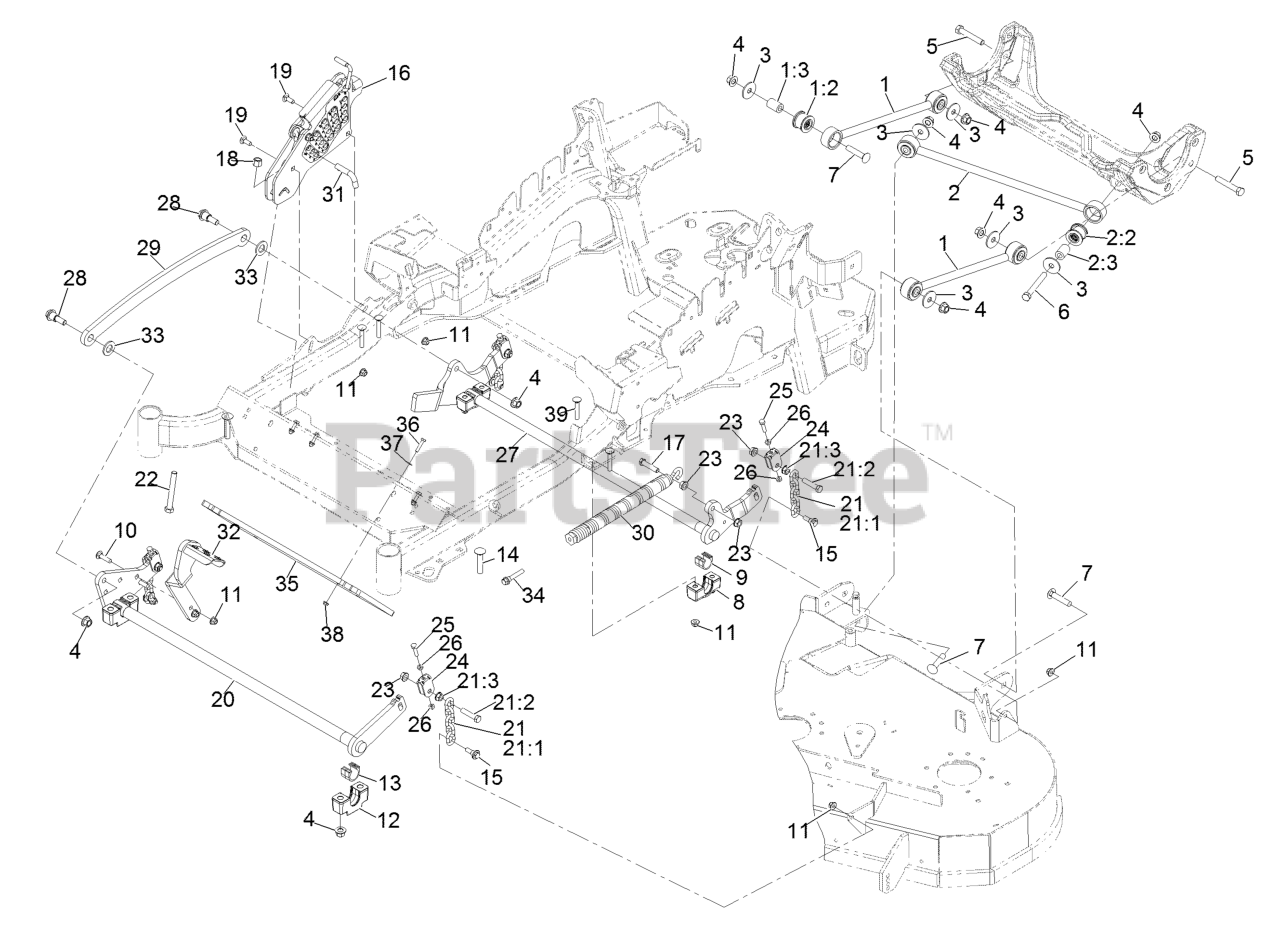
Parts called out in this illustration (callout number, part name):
1	DECK STRUT ASM
1:2	BUSHING-SUSPENSION, RUBBER
2	PANHARD ROD ASM
2:2	BUSHING-SUSPENSION, RUBBER
3	WASHER-THRUST
4	Nut-Lock 1/2-13
5	SCREW-HH
6	SCREW-HH
7	SCREW-CARR
8	SUPPORT-CROSS SHAFT, BEARING REAR
9	BEARING-CROSS SHAFT, REAR
10	SCREW-CARR
11	NUT-HF, NI
12	SUPPORT-CROSS SHAFT, BEARING
13	BEARING-CROSS SHAFT, FRON
14	Bolt-Carriage 1/2-13 X 2 1/2 Spl Neck
15	SCREW-SHOULDER, HHF
16	HOC ASM
17	SCREW-HH
18	NUT-LOCK, NI
19	BOLT-CARR
20	DECKLIFT-FRONT
21	DECK LIFT CHAIN ASM
21:1	CHAIN-LIFT, DECK
21:2	SCREW-HH
22	BOLT-TAP
24	YOKE-ADJUST, DECK
25	SCREW-HH
26	NUT-JAM
27	LIFT-DECK, REAR
28	SCREW-SHOULDER, HHF 1/2-13 X 1.12
29	LINK-LIFT, DECK
30	SPRING-EXTENSION
31	PIN-HOC
32	LEVER-FOOT
33	WASHER-FLAT
34	BOLT-SHOULDER
35	WEIGHT-TOE BOARD
36	SCREW-HH
37	WASHER-FLAT
39	Bolt-Carriage 3/8-16 X 2 1/4
